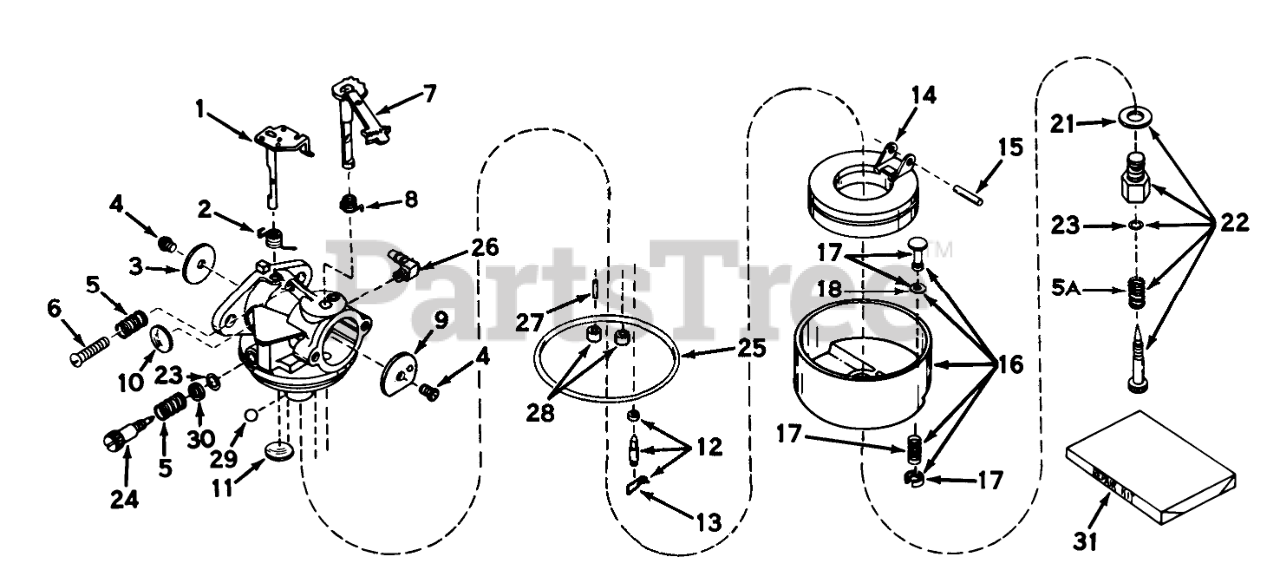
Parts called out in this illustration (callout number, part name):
1	Shaft & Lever Assy.
2	Spring, Throtte Return
3	Shutter-Throttle
4	Screw-Shutter
5	Spring-Tension
6	Screw-Throttle Crack Screw / Idle Speed
7	Shaft & Lever Ass-y Choke
8	Spring-Positioning, Choke
9	Shutter-Choke
10	Plug-Welch, Idle Mixture Well
11	Plug-Welch, Atmospheric Vent
12	Inlet Needle, Seat & Clip Assy. (Incl. No. 13)
13	Clip-Spring
14	Float,Carburetor
15	Shaft-Float
16	Bowl & Drain Assy., Float (Incl. No. 17)
17	Drain Assy. ,Bowl (Incl.No.18)
18	Gasket-Plunger, Drain
21	Washer-Bowl Nut
22	Adjustment Screw Assy., Main (Incl. Nos. 5A, 21 & 23)
23	"O"Ring
24	Screw, Idle Adj.
25	O Ring-Bowl, Float
26	Fitting Fuel Inlet
28	Plug, Cup
29	BalI, Steel
31	Kit-Repair
